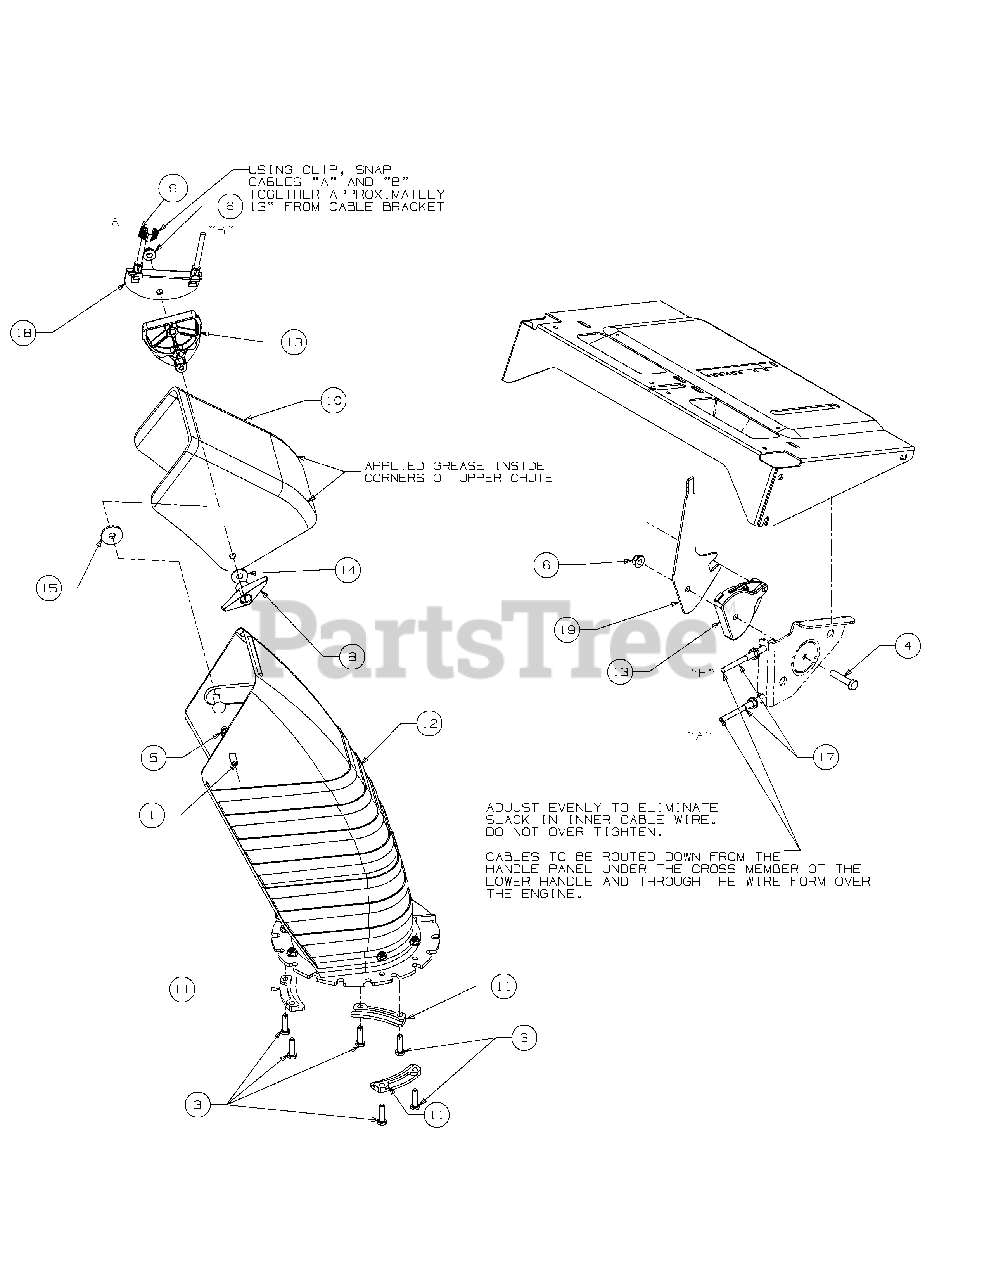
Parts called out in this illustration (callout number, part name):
1	Carriage Bolt 5/16-18 X 1.00
2	Bolt-Carriage 5/16
3	Screw-Hex 1/4-20 X
4	Screw-Hex Cap
5	Screw-Hex Tap 1/4
6	Nut-Flglk 5/16-18
7	Nut-Flglk
8	Knob-Wing Nut
9	Clip-Cable
10	Chute-Upper
11	Chute Keeper Flange
12	Lower Chute 6"
13	Cable Guide
14	Washer-Fl
15	Washer-Fl
16	Grease
17	Cable-Chute
18	Bracket-Cable
19	Handle Bracket
